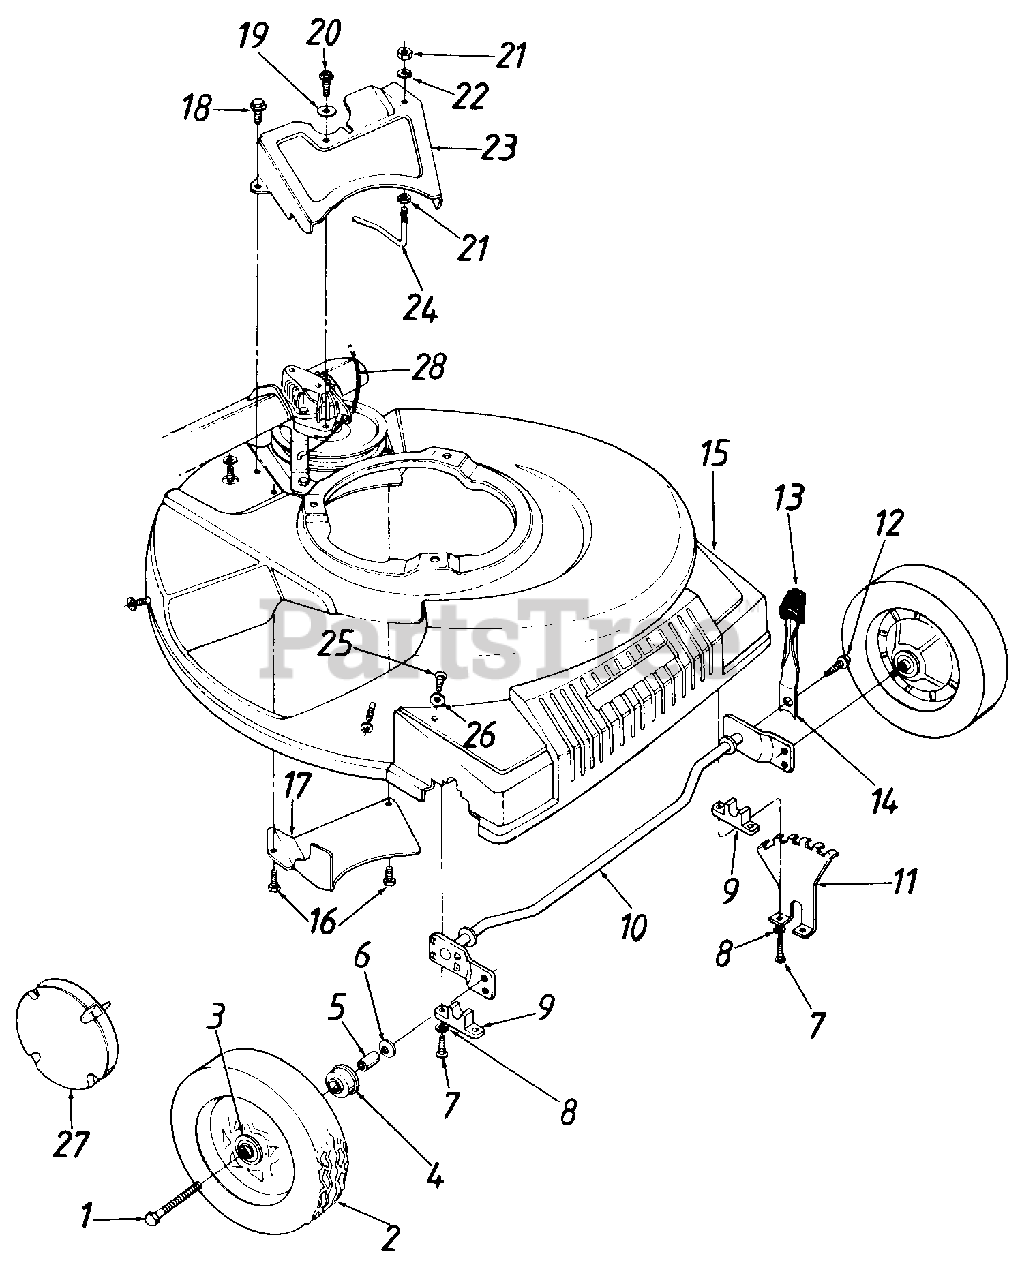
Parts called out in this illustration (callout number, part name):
1	Hex Bolt 3/8-16 x 1.75" Lg.
2	Wheel Ass'y. Comp. 8 x 1.75
3	Flange Ball Brg. 3/8" I.D.
4	Flange Ball Brg. .501" I.D.
5	Spacer
6	Bell-Wash. .400" I.D. x .88
7	Hex Wash. Hd. B-Tap Scr. 1/4-20
8	L-Wash. 1/4" I.D.
9	Block Bushing
10	Axle Ass'y.
11	Height Adj. Bracket
12	Hex Wash. Hd. B-Tap Scr. 1/4-20 x .75" Lg.
13	Knob
14	Spring Lever
15	Plastic Front End
16	Hex B-Tap Scr. 1/4-.38"
17	Belt Cover
18	Hex Wash. Hd. TT-Scr. 1/4-20
19	Bell-Wash. .265" I.D. x .7:5"
20	Hex Wash. Hd. B-Tap Scr. 1/4 x.62"
21	Hex Nut 1/4-20 Thd.
22	L-Wash. 1/4 I.D.
23	Transmission Belt Guard
24	S.P. Belt Guard
25	Truss B-Tap Scr. 5/16 x .75" Lg.
26	Bell-Wash. 5/16" I.D. x 5/8
27	Hub Cap
28	S.P. Cable 50" Lg.
